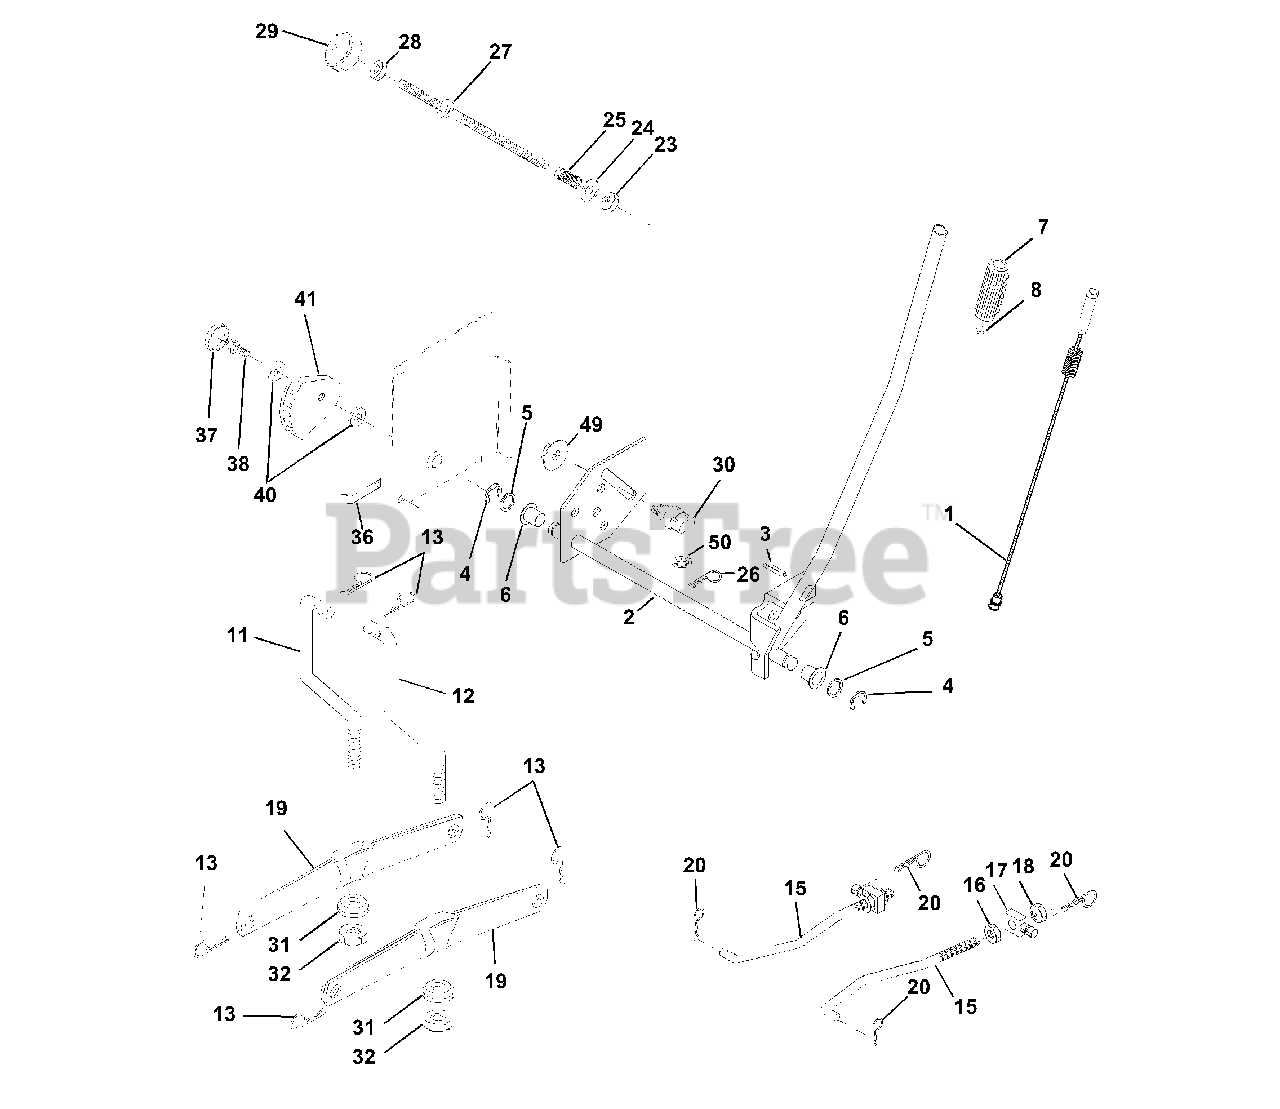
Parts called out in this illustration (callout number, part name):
1	Wire Asm Inner/Sprg W/plunger LT
2	Shaft Asm Lift RH w/Inf
3	Pin Groove 1 500 Zinc
4	E Ring #5133-62
5	Washer 21/32 X 1 X 21 Ga
6	Bearing Nylon Blk 629 Id
7	Grip Handle
8	Button Plunger Yellow
11	Link Lift LH Fixed Length
12	Link Lift RH Fixed Length
13	Retainer Spring
15	Link Front
16	Nut Jam Hex 1/2-13 Unc
17	Trunnion Blk Zinc
18	Nut Lock W/Wsh 1/2-13 Unc
19	Arm Suspension Rear
20	Retainer Spring
23	Nut Special
24	Washer 13/32 X 5/8 X 16 Ga
25	Spring 2-1/8"
26	Retainer Clip
27	Rod Adj Lift Zinc 7.49 Wrk Lg
28	Nut Hex Jam 3/8-16 Unc
29	Knob Inf 3/8-16 Unc Blk W/sym
30	Trunnion Infin Height
31	Bearing Pvt Lift Spherical
32	Nut Crownlock 3/8 - 24
36	Pointer Height Indicator
37	Plug Hole Blk 1.485/1.515 Dia.
38	Screw 5/16-18 x 1
40	Washer 11/32 x 1-1/2 10 Ga.
41	Indicator Height STLT
49	Nut Hex Flange Lock
50	Nut PUsh Phos & Oi
